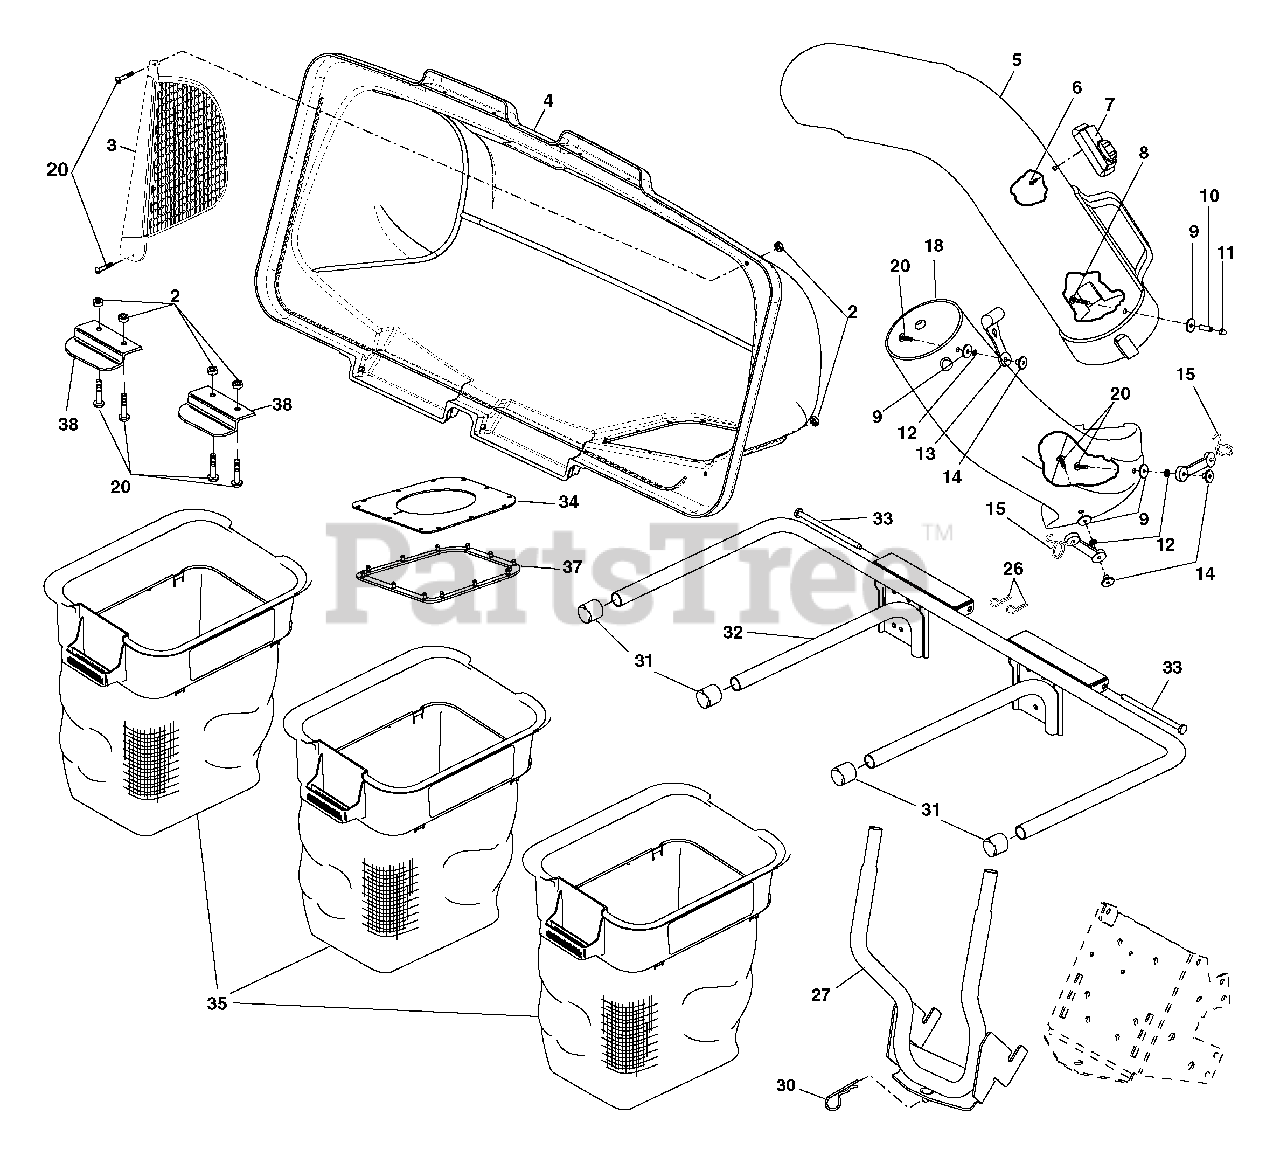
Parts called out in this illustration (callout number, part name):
2	Nut, Crownlock #10-24
3	Screen, Cover
4	Cover Assembly
5	Chute, Upper
6	Screw, Special #10-14x1/2
7	Full Bag Indicator
8	Screw, #10-24 x 1-1/8
9	Washer 3/16x3/4x16 Ga.
10	Spacer, Split
11	Nut, Acorn #10-24
12	Washer, lock
13	Latch, Chute
14	Nut, Weld
15	Latch
18	Chute, Lower
20	Screw #10-24 x 5/8
26	Spring, Retainer
27	Support Assembly
30	Spring, Retainer
31	Plug, Tubing End
32	Bagger, Frame
33	Pin, Hinge
34	Gasket, Cover
37	Seal, Cover
38	Latch Handle, Cover
